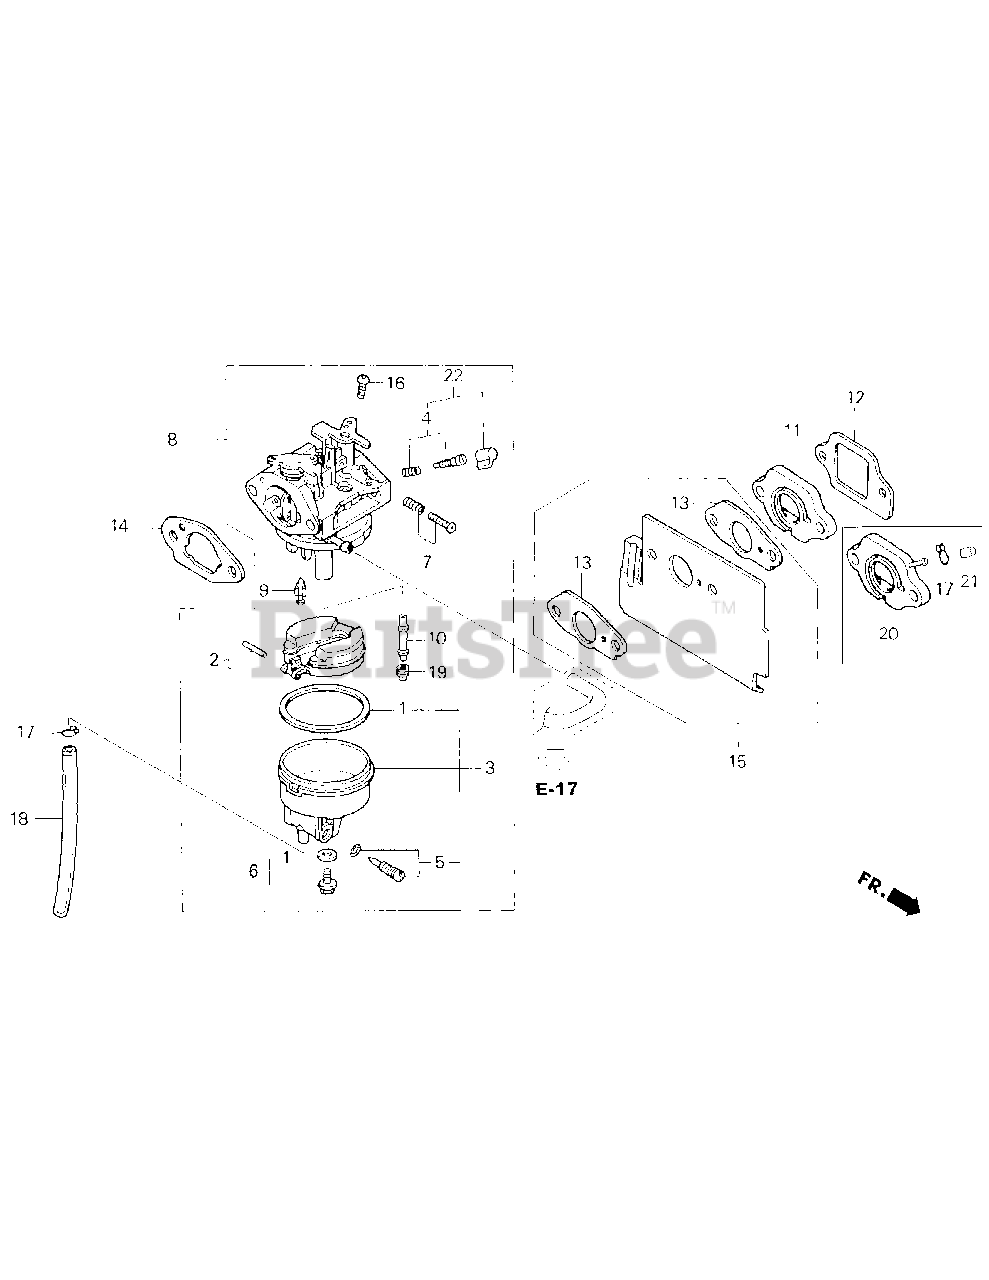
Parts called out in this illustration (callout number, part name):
1	GASKET SET
3	CHAMBER SET, FLOAT
5	SCREW SET, DRAIN
6	SCREW SET B
8	CARBURETOR ASSY.
9	VALVE, FLOAT
10	NOZZLE, MAIN
11	INSULATOR, CARBURETOR
12	GASKET, INSULATOR
13	GASKET, CARBURETOR
14	GASKET, CARBURETOR (CHOKE SIDE)
15	GUIDE, AIR
16	SCREW, PAN (5X6)
17	CLIP, TUBE (B6.5)
18	BULK HOSE, VINYL (4X7X8000) (4X7X150)
19	JET, MAIN (#60)
19	JET, MAIN (#62)
19	JET, MAIN (#65)
22	SCREW SET (CARBURETOR NO.)
